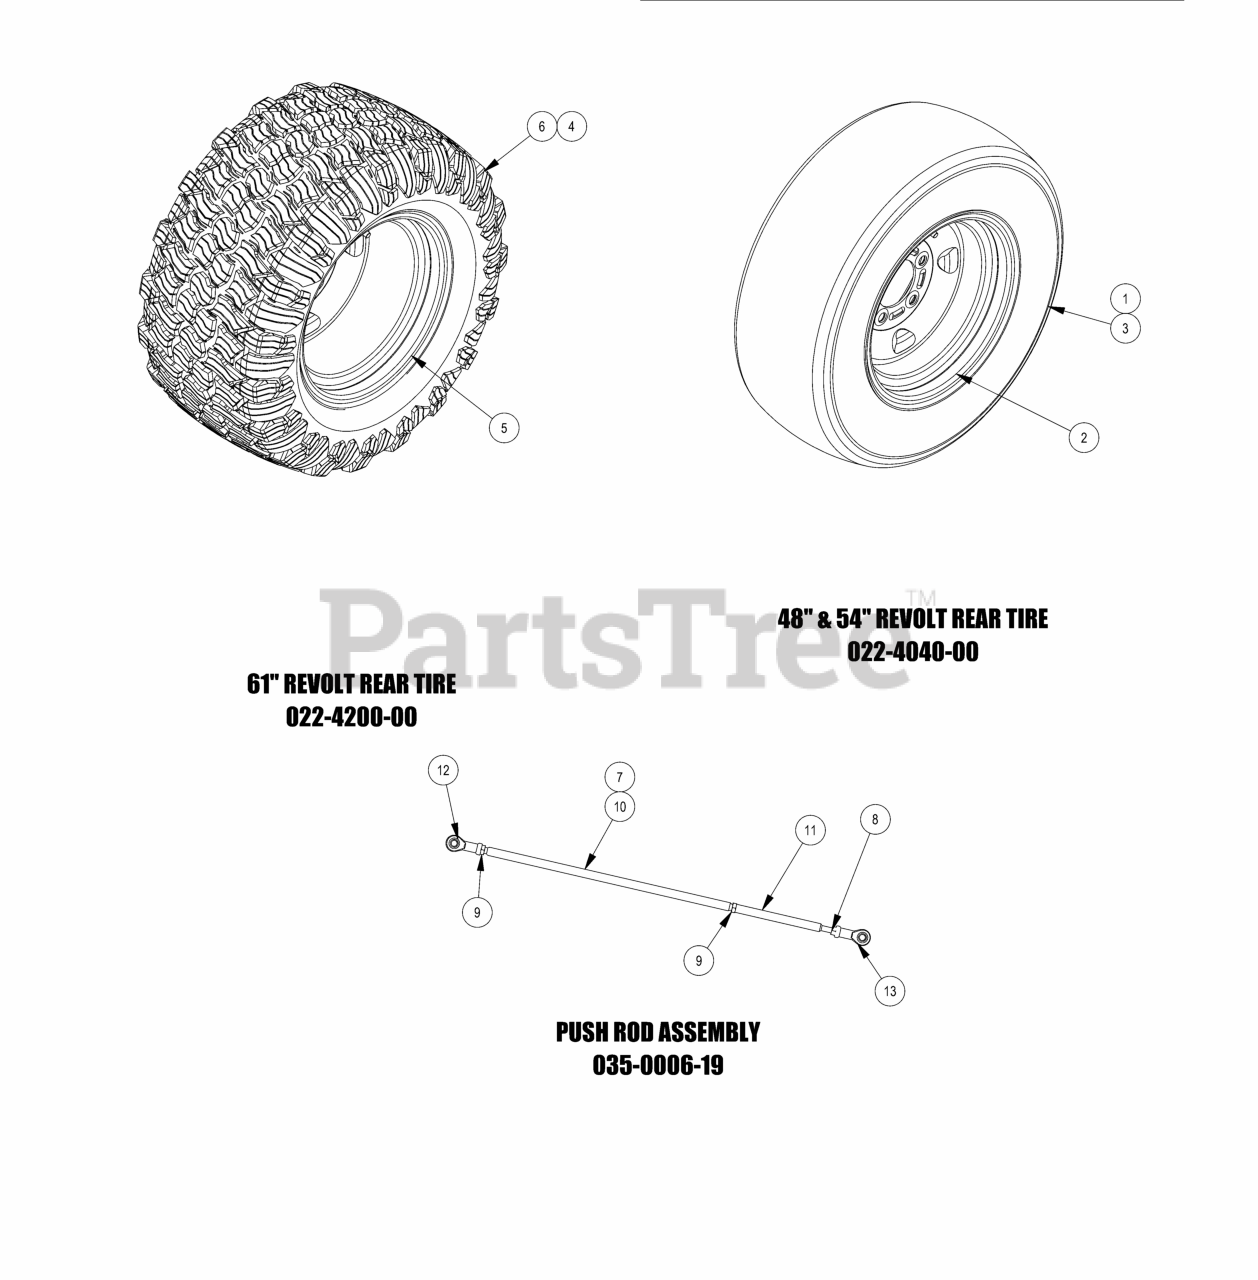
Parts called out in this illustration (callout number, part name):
1	23x9-12 Reaper Turf Tire & Wheel Assembly
2	12x7" Black Wheel
3	23x9-12 Reaper Turf Tire Only
4	23x11-12 Reaper Turf Assembly
5	12x8.5 Black Wheel
6	Tire, 23/11x12 Reaper Turf
7	2019 Revolt Push Rod Assembly
8	5/16 LH Nut
9	3/8-24 HEX NUT ZINC YELLOW
10	2019 Revolt Push Rod
11	2019 Renegade Push Rod Adjuster
12	Spherical Rod End - Outlaw
13	Spherical Rod End - Outlaw
